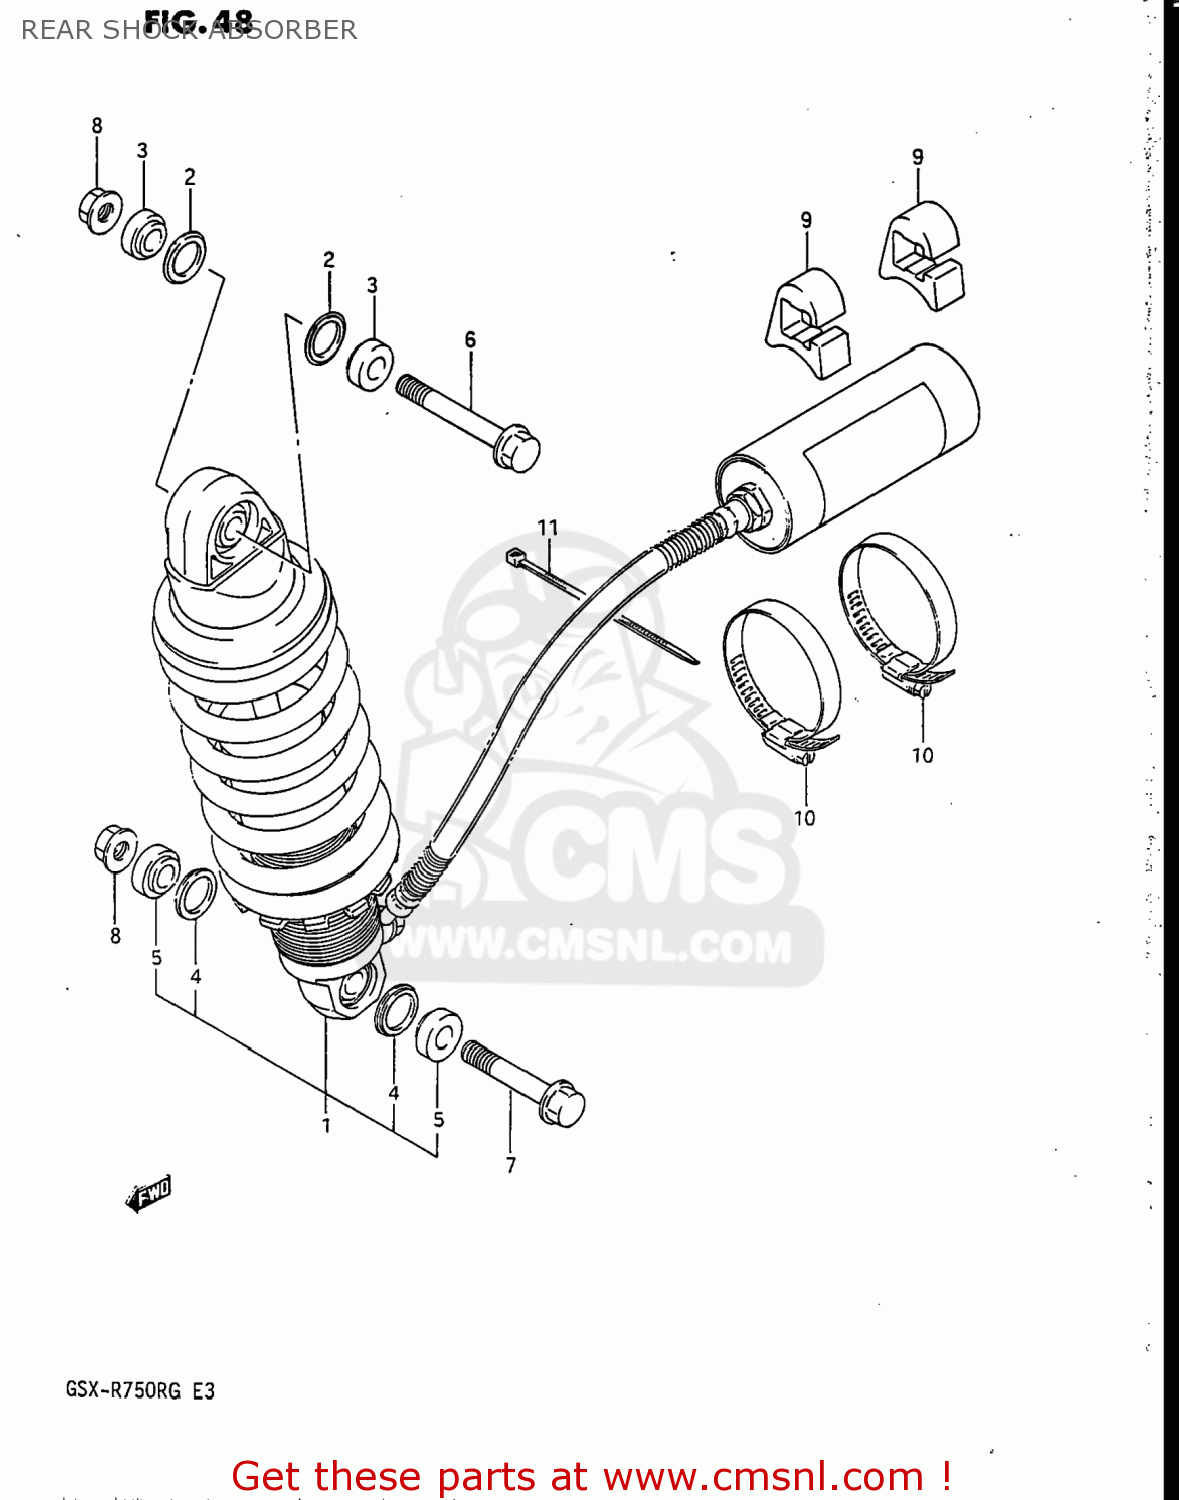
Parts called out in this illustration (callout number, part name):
1	ABSORBER ASSY,RR SHOCK
2	SEAL DUST
3	COLLAR
4	SEAL,DUST RR SHOCK ABSORBER
5	COLLAR
6	BOLT
7	BOLT(10X48)
8	NUT
9	CUSHION,RESERVOIR TANK
10	CLAMP
11	CLAMP(L:145)
